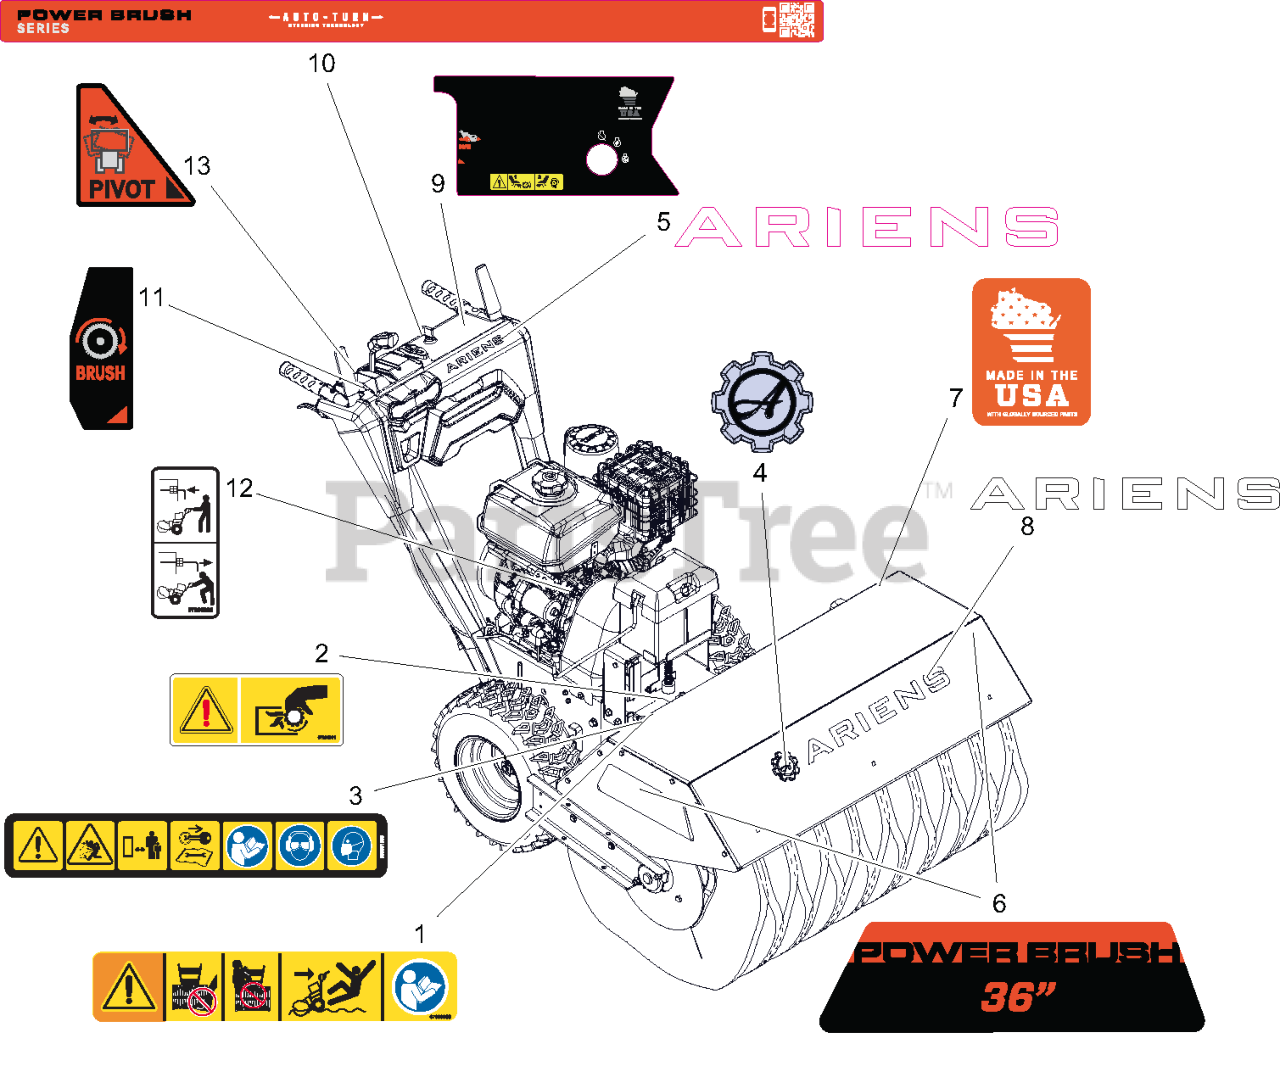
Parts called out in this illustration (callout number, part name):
1	DECAL, DANGER -POWER BRUSH-CE
2	DECAL, PTO WARNING
3	DECAL, SAFETY, DASH, BRUSH
4	DECAL, ARIENS - GEAR BADGE
5	DECAL- ARIENS - 7.46"
6	DECAL, POWERBRUSH - 36
7	DECAL- MADE IN USA
8	DECAL, ARIENS - 19.0"
9	DECAL- CONTORL - LG BRUSH 12V
10	DECAL- DASH - BRUSH HYDRO
11	DECAL, CONTROL - BRUSH
12	DECAL, HYDRO BRUSH BYPASS
13	DECAL, CONTROL - BRUSH PIVOT
